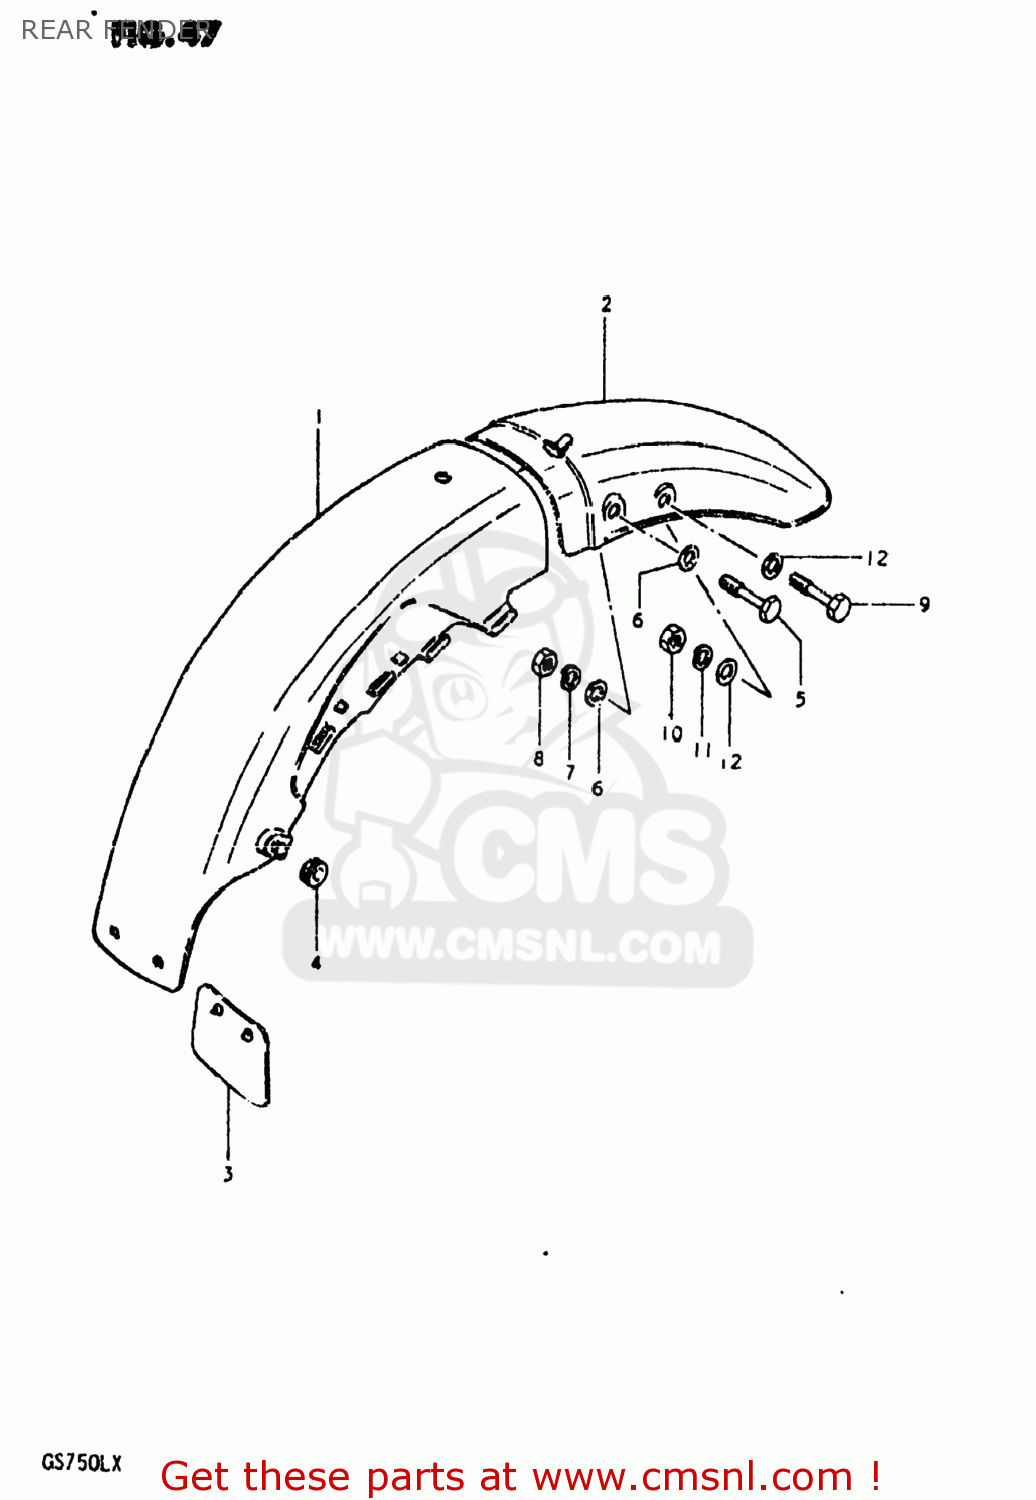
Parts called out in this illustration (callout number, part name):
1	FENDER,REAR
2	FENDER,REAR
3	GUIDE,RR FENDER MUD
4	CUSHION
5	BOLT
6	WASHER
7	LOCK WASHER
8	NUT
9	BOLT
10	NUT 8MM
11	LOCK WASHER
12	WASHER
